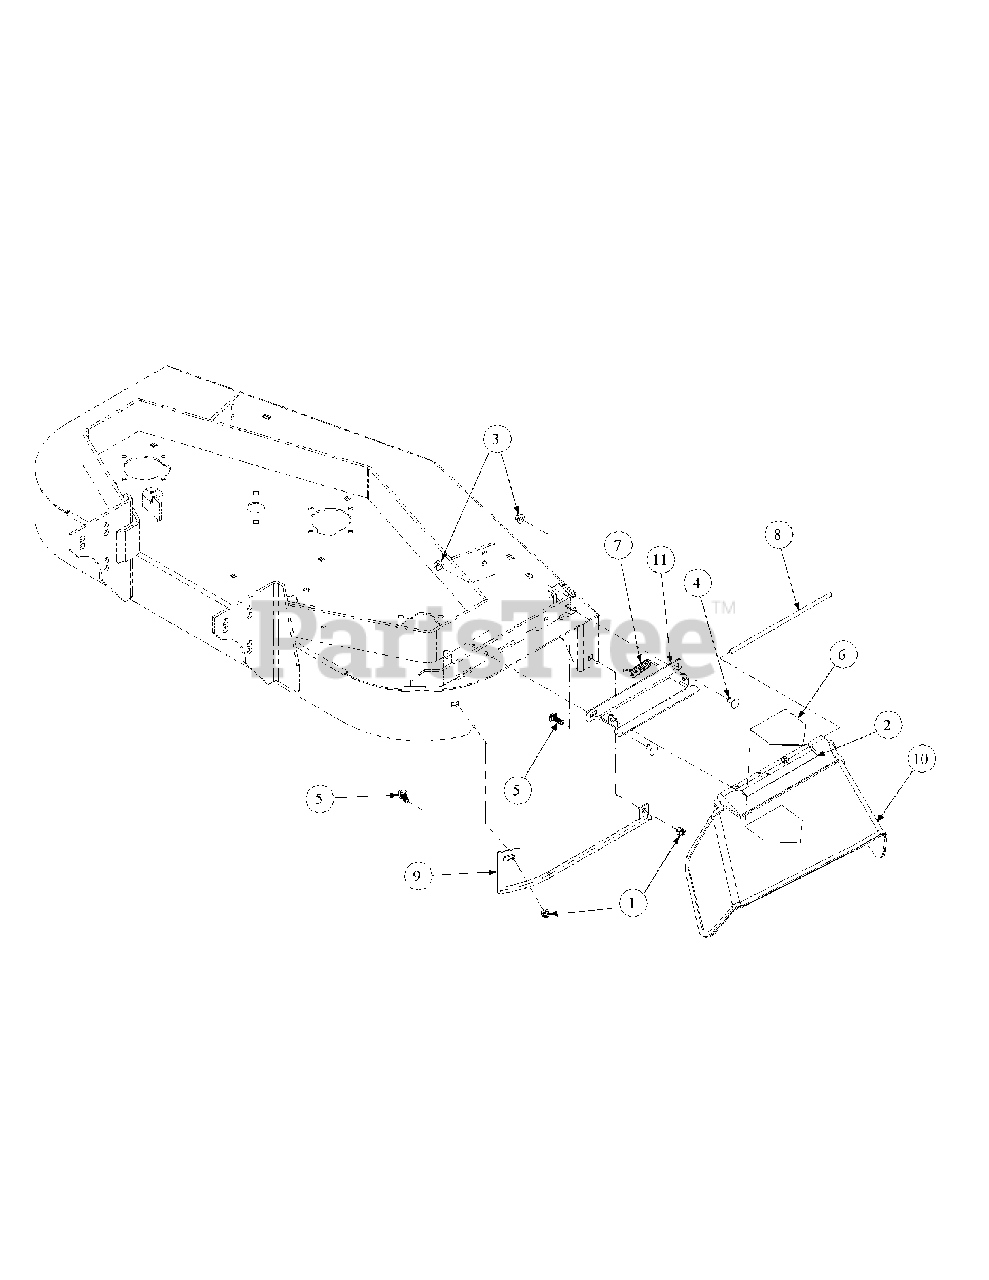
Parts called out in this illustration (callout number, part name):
1	Lock Nut, Nylon Insert, 3/8-16
2	Decal, Cut LIne
3	Flange Lock Hex Nut, 3/8-16
4	Carriage Bolt, 3/8-16 x .75
5	Carriage Bolt, 3/8-16 x 1
6	Decal, Danger Hands and Feet
7	Torsion Spring
8	Chute Deflector Rod
9	Stiffner Assembly, 48
10	Deflector Chute
11	Deflector Chute Bracket
